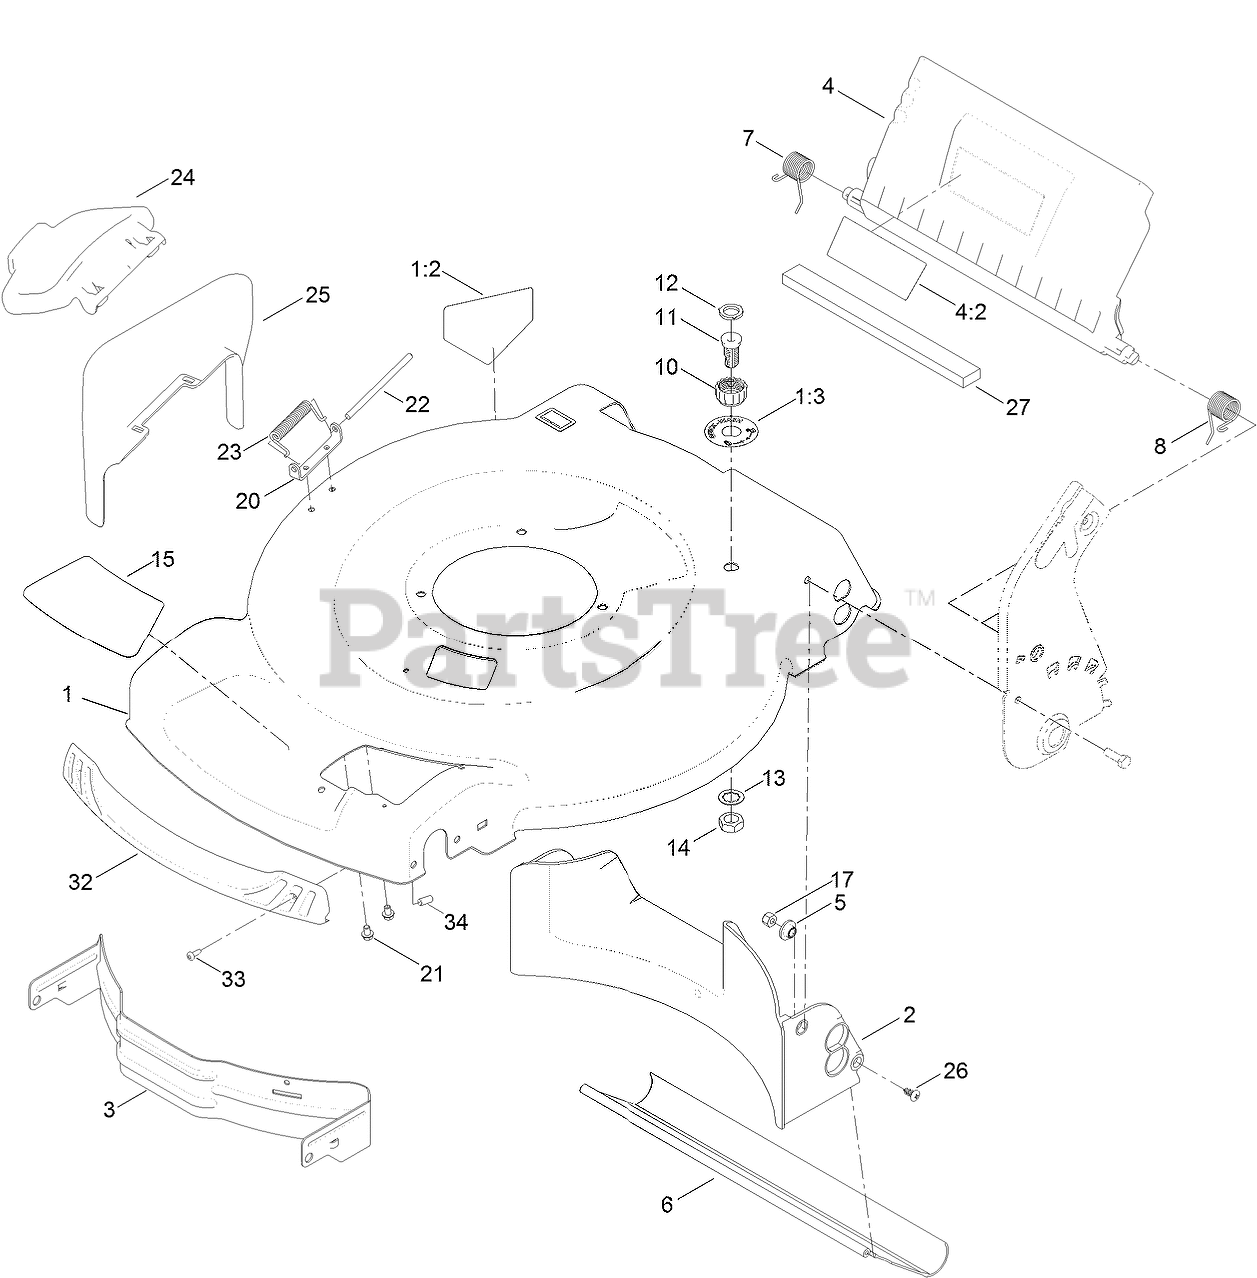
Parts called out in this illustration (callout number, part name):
1	HOUSING ASM
1:2	DECAL-DANGER
1:3	DECAL-PORT, WASHOUT
2	BAFFLE-REAR
3	BAFFLE-FRONT
4	REAR DEFLECTOR ASM
4:2	DECAL-WARNING
5	WASHER-STEPPED, BAFFLE
6	SHIELD-TRAILING
7	SPRING-TORSION
8	SPRING-TORSION
10	COUPLING-HOSE, WASHOUT PORT
11	PORT-WASHOUT
12	WASHER-SEAL, WASHOUT PORT
13	WASHER-TOOTH, INTERNAL
14	NUT-JAM
15	DECAL-DECK
17	NUT-LOCK, NI
20	BRACKET-COVER
21	SCREW-HWH
22	ROD-COVER
23	SPRING-TORSION
24	DEFLECTOR-SIDE
25	CHUTE-DISCHARGE, SIDE
26	SCREW-PTH
27	FOAM-SEAL
32	BUMPER
33	SCREW-FORMING, THREAD
34	CAP-PLUG
